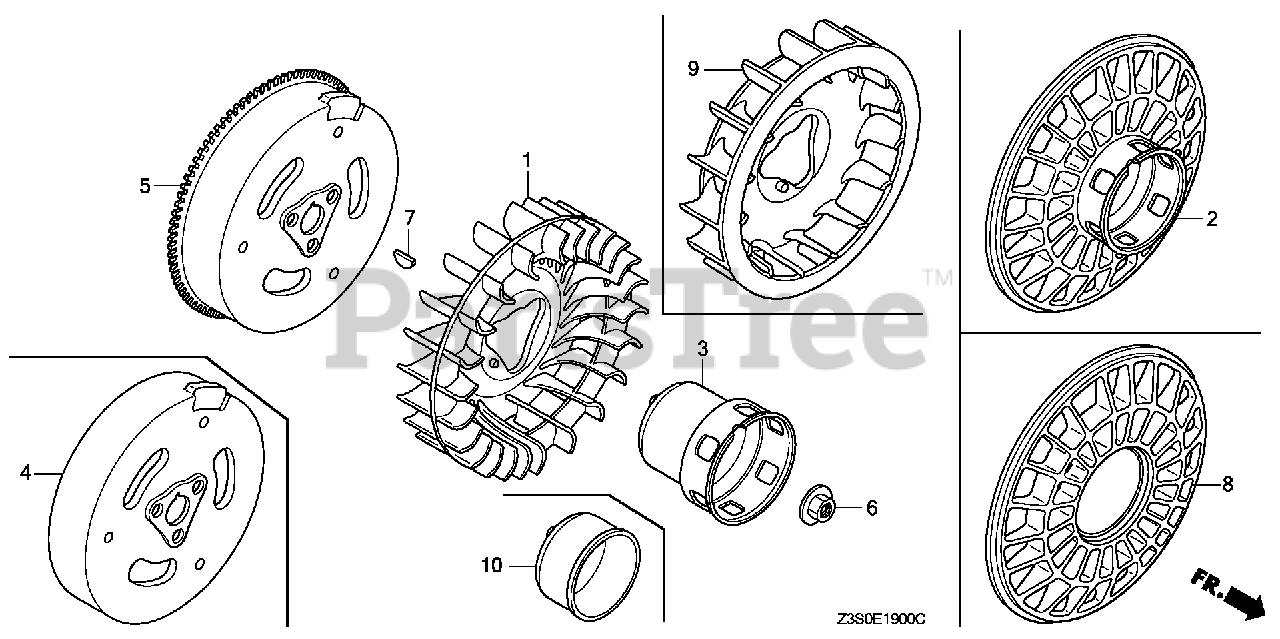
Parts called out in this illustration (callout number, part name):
1	FAN, COOLING
3	PULLEY, STARTER
6	NUT, SPECIAL (16MM)
7	KEY, SPECIAL WOODRUFF (25X18)
